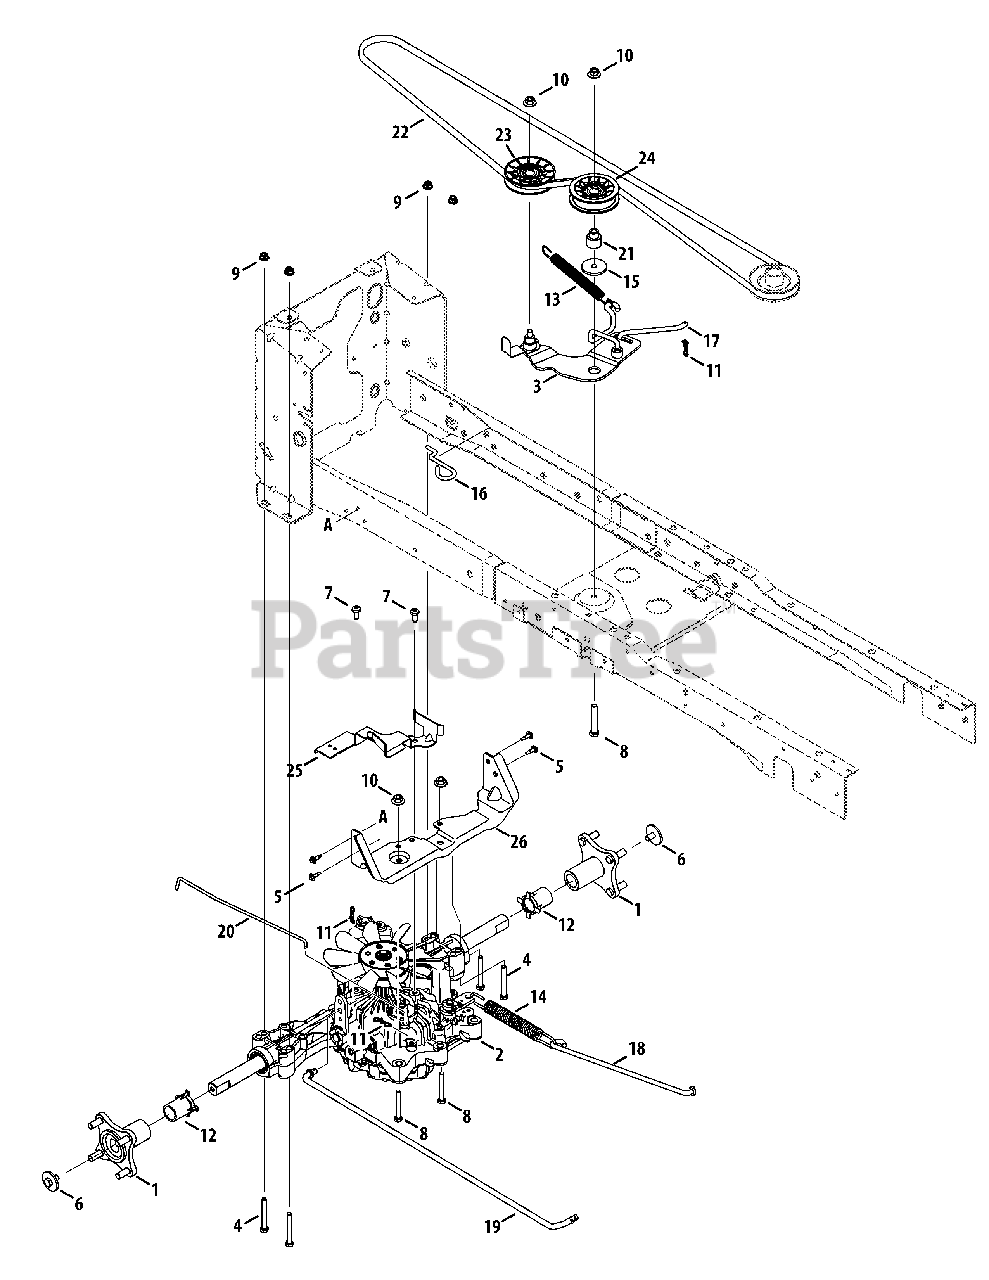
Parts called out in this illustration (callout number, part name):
1	Hub Assembly, Wheel
2	Transmission, Tuff Torq K58
3	Idler bracket Assembly
4	Hex Screw, 5/16-18, 2.75, Gr5, Std
5	Screw, M6-1 x .625
6	Hex Cap Screw, 3/8-16 x .750
7	Screw, Self-tapping, 5/16-18, 0.750
8	Hex Screw, 3/8-16, 2.25, Gr5
9	Nut, Flange Lock, 5/16-18, Nylon
10	Flange Lock Nut, 3/8-16
11	Pin, Cotter, Bow-Tie 72
12	Sleeve, 1.02 ID x 1.75
13	Spring, Extension, .700 Dia x 8.41
14	Spring, Extension, .90 Dia x 8.14
15	Shoulder Spacer, .884 x .190
16	Deck Spring Rod
17	Idler Link
18	Rod, Brake, Tuff Torq
19	Rod, Control, Tuff Torq
20	Rod, Transmission, Bypass
21	Shoulder Spacer
22	Belt, V-Type
23	Idler Pulley, 3.56 OD
24	Idler Pulley, 3.00 OD
25	Belt Keeper Bracket
26	Transmission Bracket
